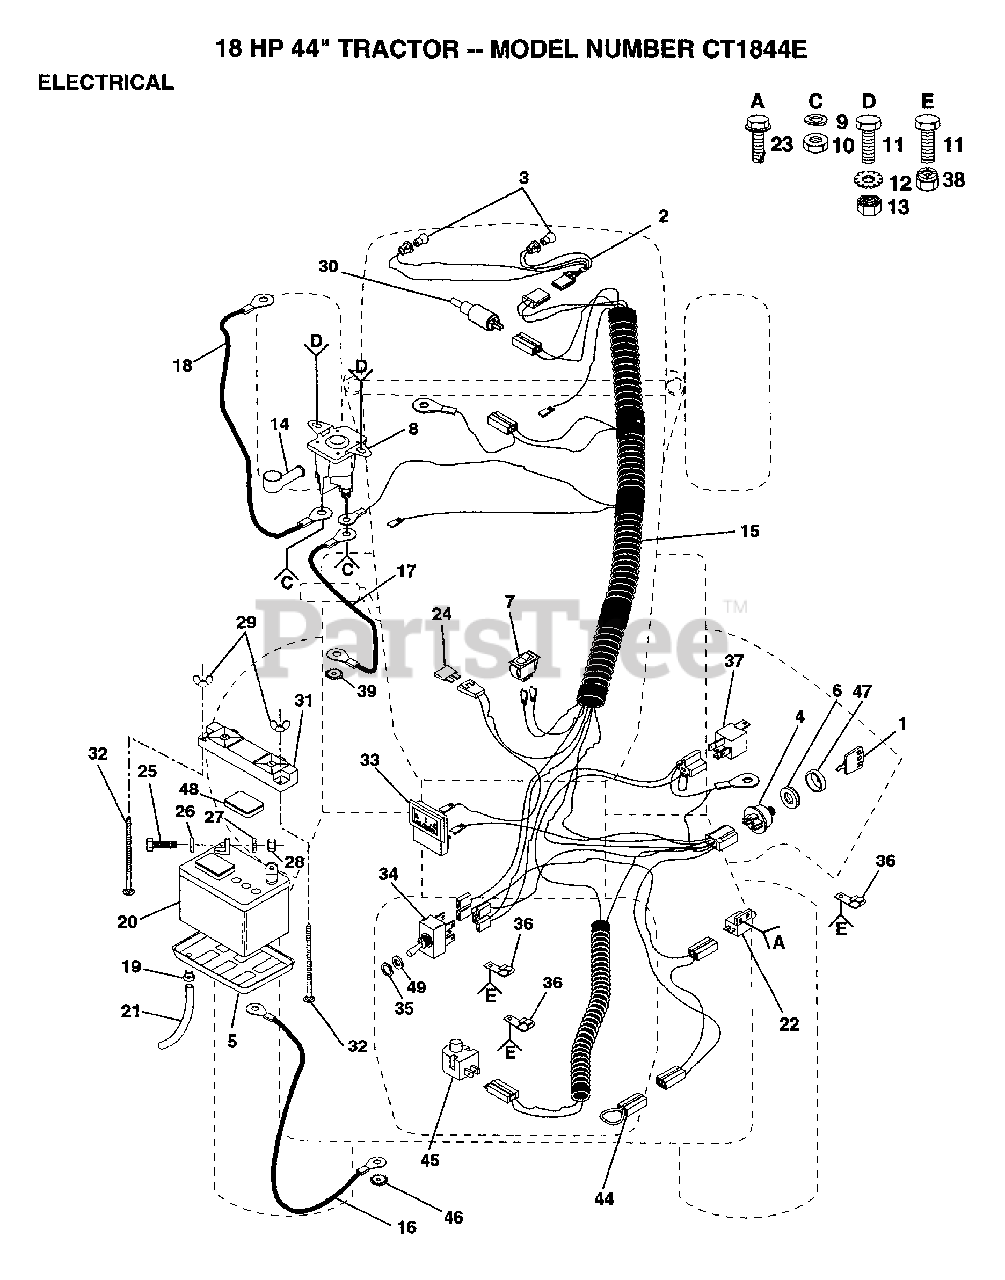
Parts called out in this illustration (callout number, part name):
1	KEY
2	"HARNESS,LIGHT SOC"
5	"TRAY T, BATTERY"
6	NUT IGNITION
7	SWITCH LT
10	NUT
11	BOLT
13	NUT
15	HARNESS.IGN.B&S
16	CABLE T
17	CABLE LT
18	"CABLE T, BATTERY"
19	HOSE CLAMP T
21	"DRAIN TU T, BATT"
22	SWITCH-INTER. GT
23	SCREW
24	FUSE HYT
25	BOLT LT
26	WASHER
27	LOCKWASHER
30	DIODE ASM.
32	BOLT
34	"SWITCH,PTO"
35	HEX NUT T
36	CLIPT
37	RELAY ASSY T
39	LOCKWASHER
45	SWITCH SEAT
46	LOCKWASHER
48	"CAP,BATTERY "
49	WASHER
